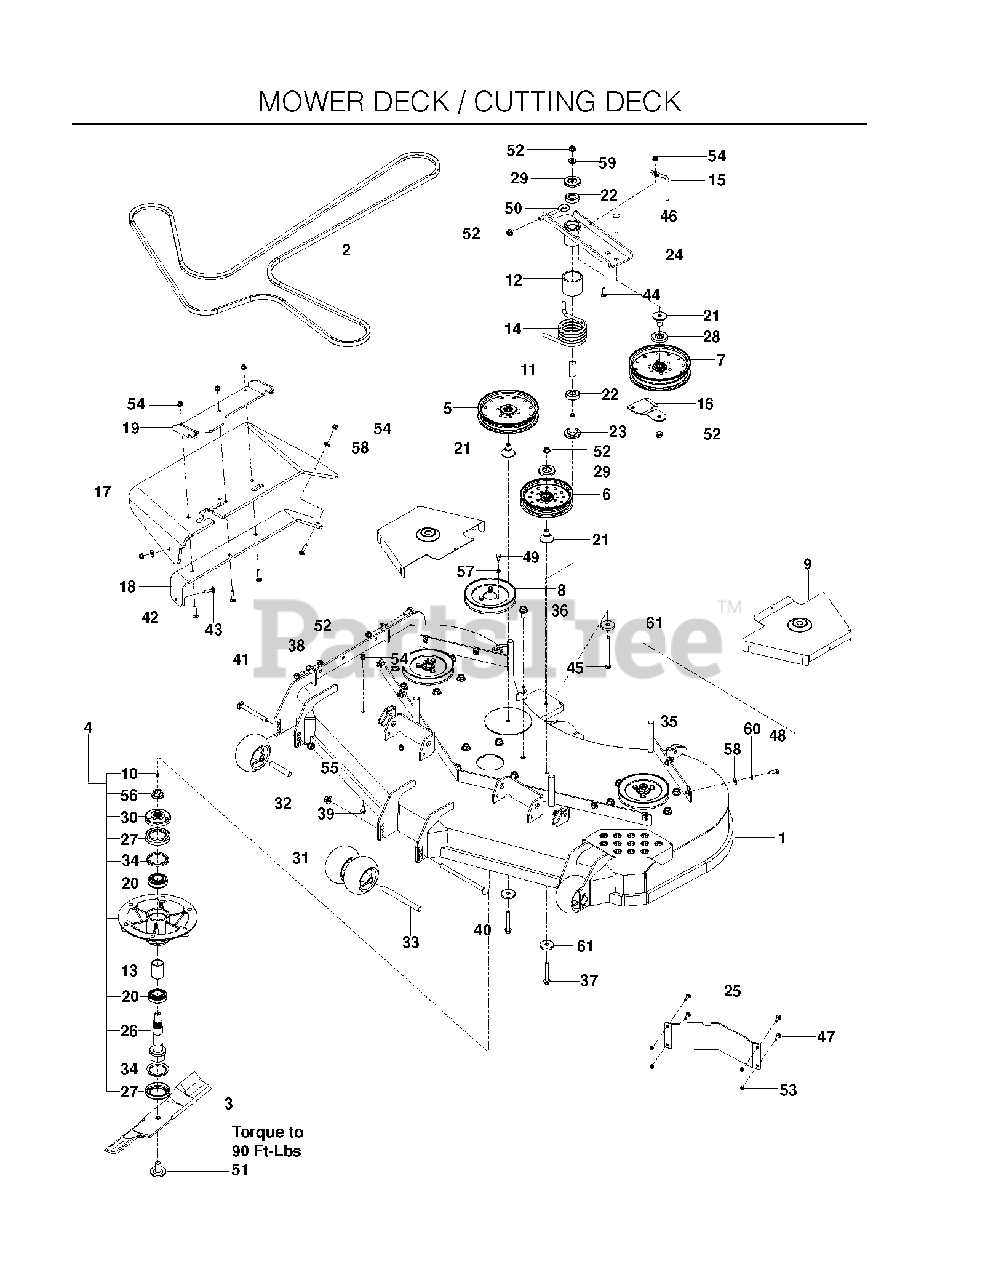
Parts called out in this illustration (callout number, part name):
1	DECK W/SAFETY DECALS 60"
2	BELT, "B", 176
4	SPINDLE ASM. 10"
5	PULLEY - 7" NARROW
6	PULLEY IDLER, 6" NARROW
7	PULLEY - IDLER 7"
8	PULLEY - 6.57
9	SHIELD, BELT, 60" BLUE
10	ZERK
11	SPACER, IDLER BEARINGS
12	SPACER, IDLER PIVOT
13	SPACER - BEARING
14	SPRING, TORSION, IDLER
15	BELT KEEPER
16	BELT GUIDE, BLK
17	CHUTE, DISCHARGE 48-52
18	BRKT, CHUTE SUPPORT BLACK
19	BRKT - CHUTE MTG BLACK
20	BEARING - 206KRR8
21	BEARING, IDLER ARM
23	BEARING, IDLER PIVOT
25	BAFFLE, DIVERTER 54"/60" LH
26	SHAFT - SPINDLE
27	CUP - DEBRIS
28	SHIELD, DUST
29	DUST SHIELD
30	HUB - PULLEY
31	ROLLER, GAUGE .635 BORN
32	TUBE, ROLLER AXLE
33	TUBE, ROLLER AXLE LONG
34	V-RING, 55MM
35	U-CLIP 5/16-18 NUT RETAINER
36	HHFS 1/2-13 X 1 GR5 ZD
37	HHFS 3/8-16 X 2 3/4
38	HHFS 3/8-16 X 1 GRD 5 ZD
39	HHFS 5/16-18 X 3/4
40	RHSNB 1/2-13 X 8 GR5 ZD
41	RHSNB 1/2-13 X 4.75 GR5 ZD
42	RHSNB 5/16-18 X 1-1/2 GR 5 ZD
43	BOLT, CARRIAGE 5/16X1-1/4
44	RHSSNB 5/16C X 1.0
45	HCS 3/8-16 X 4-1/2 GR 8 ZD
46	CARRIAGE BOLT 3/8-16 X
48	HCS 5/16C X 1
49	HCS 5/16-18 X 1/2 GR 5 ZD
50	EYE BOLT, 3/8 X 4"
51	BLADE BOLT/WASHER
52	NUT 3/8-16 HEX FLG NYLOC ZD
53	NUT 1/4-20 NYLOC
54	5/16-18 NYLOC FLANGE NUT
55	NUT, 1/2-13 HEX FLG NYLOC ZD
56	NUT FLANGE 3/4-16
57	WASH 5/16 DISC SPRING ZD
58	WASHER 5/16 FLAT
59	WASHER, 3/8 THICK
60	WASHER 5/16 LOCK
61	SPINDLE WASHER
